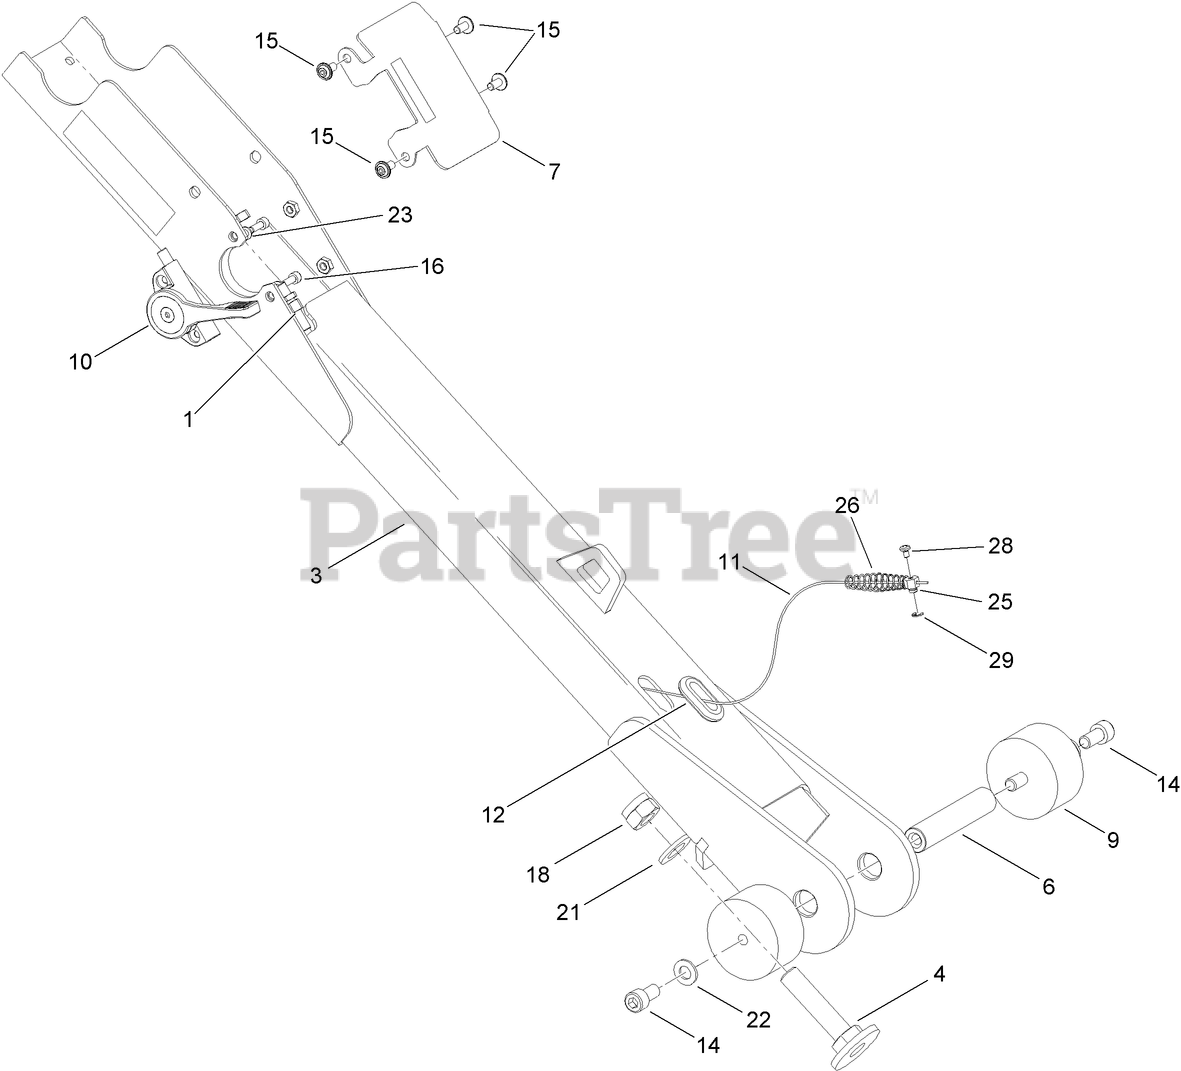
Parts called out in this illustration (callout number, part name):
1	GUIDE-CABLE
3	CONTROL ARM ASM
4	SCREW-STOP
6	BAR-PIN
7	PLATE-COVER
9	MOUNT-RUBBER
10	LEVER-THROTTLE
11	CABLE-THROTTLE
12	GROMMET
21	WASHER
22	WASHER
23	WASHER
25	NUT-WIRE
26	SPRING
29	BAR-RING
